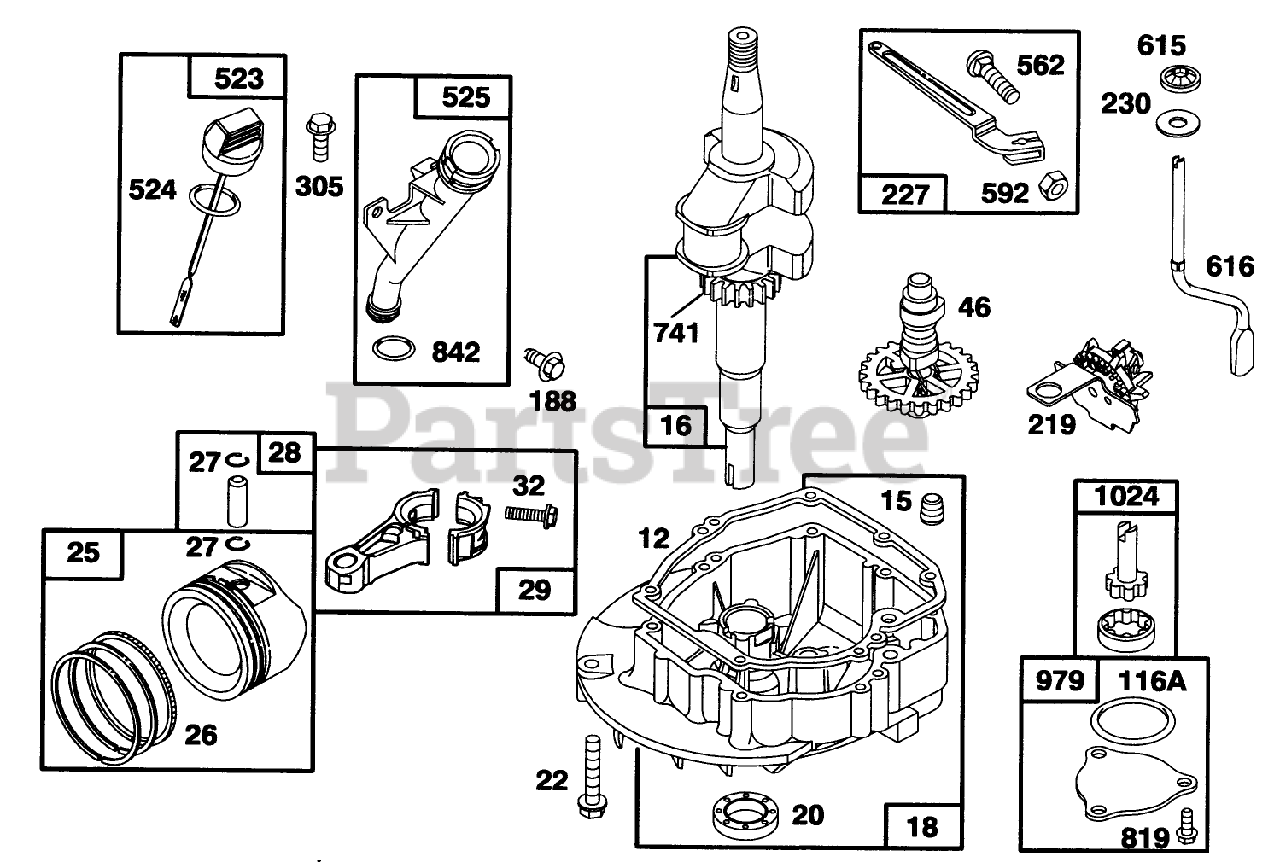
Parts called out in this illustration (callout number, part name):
98A	SPEED ADJUST. SCREW ASM
163	AIR CLEANER GASKET
188	Screw-Cap
201	GOVERNOR LINK
209	GOVERNOR SPRING
529	TUBE - BREATHER
535	FILTER ELEMENT
618	RETURN SPRING
620	CARBURETOR BRACKET
621	STOP SWITCH
966	AIR CLEANER BASE
968	AIR CLEANER COVER
969	AIR CLEANER SCREW
971	AIR CLEANER SCREW
